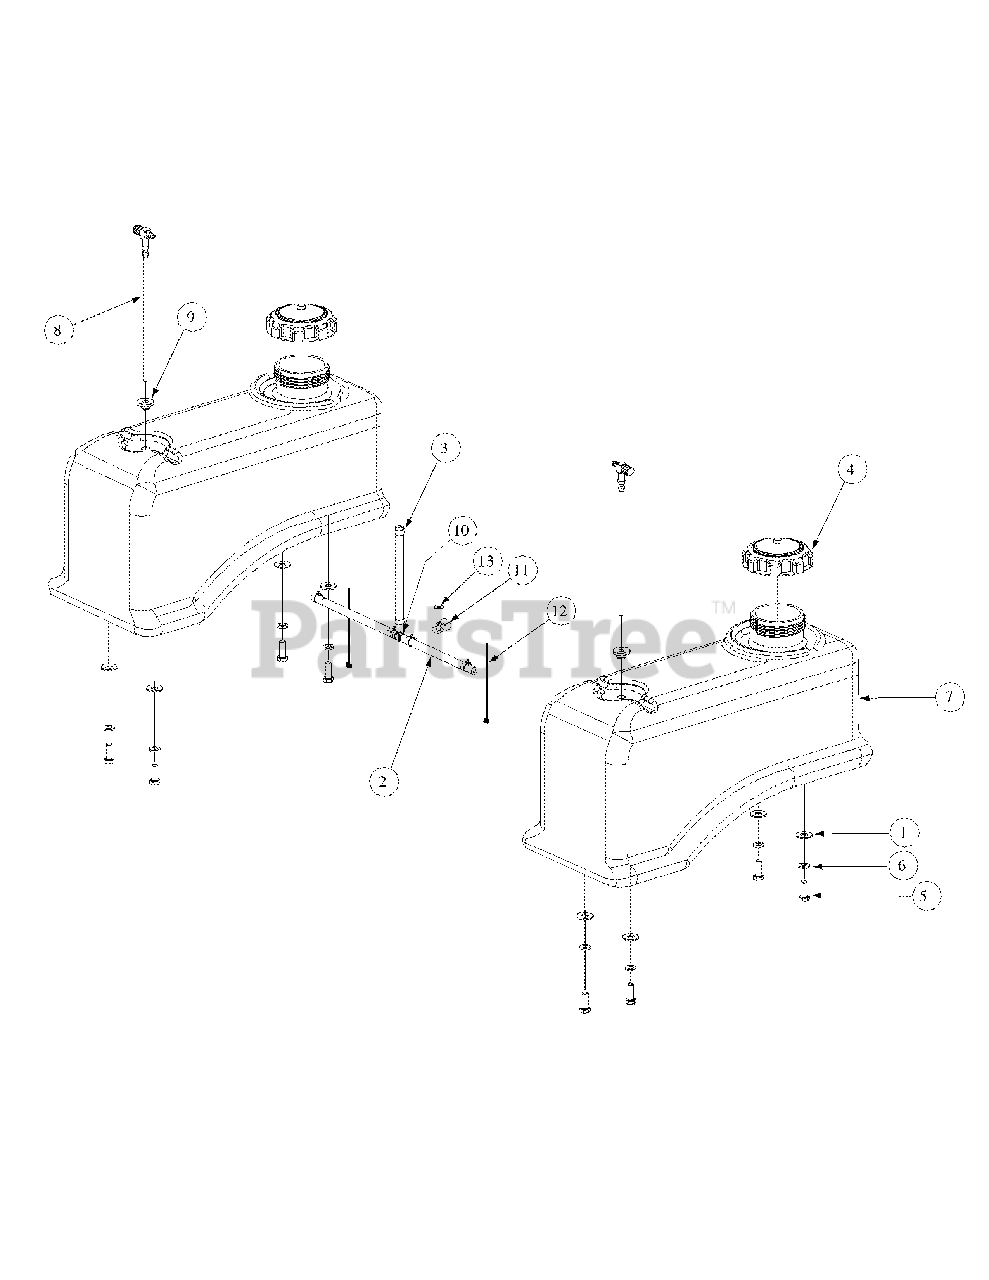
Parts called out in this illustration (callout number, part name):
1	Flat Washer, .406 ID, 1.0 OD, .105
3	Clamp, Union
4	Fuel Cap, 3.5
5	Hex, Cap Screw, 3/8-16, .88
6	Lock Washer, 3/8
7	Fuel Tank
8	Fuel Fitting
9	Grommet, Fuel Tank
10	Tee Fitting, Fuel
11	Clamp, 1/2 Tubing
12	Cable Tie
13	Flat Washer, 1.4 x .630 x .0515
